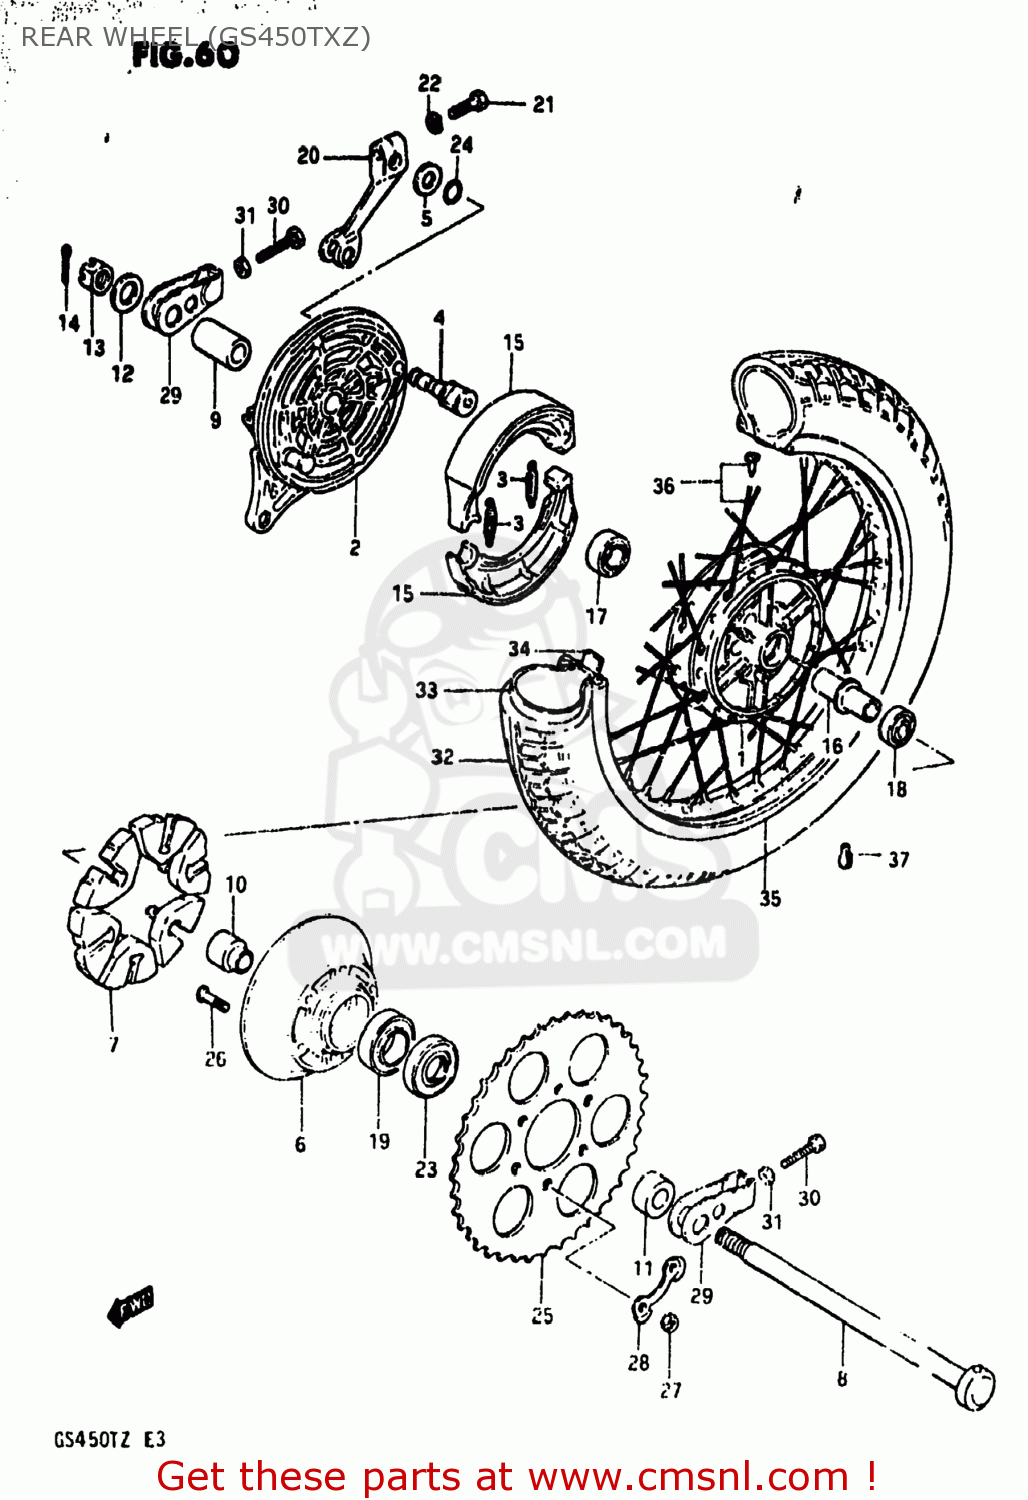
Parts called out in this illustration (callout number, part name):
1	DRUM,REAR HUB
2	PANEL,REAR HUB
3	SPRING,BRAKE SHOE
4	CAM,FRONT BRAKE
5	WASHER (15X24X1.6)
6	DRUM,REAR SPROCKET MOUNT
7	ABSORBER,RR HUB SHOCK
8	AXLE,REAR
9	SPACER(17.5X28X44.8)
10	SPACER,REAR HUB BEARING
11	SPACER(17X30.5X22.3)
12	WASHER (17X30X3.2)
13	NUT
14	PIN,COTTER
15	SHOE SET,BRAKE (MCA)
16	SPACER
17	BEARING
18	BEARING
19	BEARING
20	LEVER,RR BRAKE CAM
21	BOLT
22	LOCK WASHER
23	SEAL,OIL(30.5X52X8)
24	O-RING,BOSS
25	SPROCKET,REAR (NT:43)
26	NUT
27	NUT
28	WASHER
29	ADJUSTER,CHAIN
30	BOLT 8X50
31	NUT
32	TIRE
33	TUBE ASSEMBLY,WHEEL,INNER
34	PROTECTOR,WHEEL,INNER
35	RIM,REAR WHEEL
36	SPOKE SET,REAR WHEEL
37	BALANCER,WHEEL (B)
